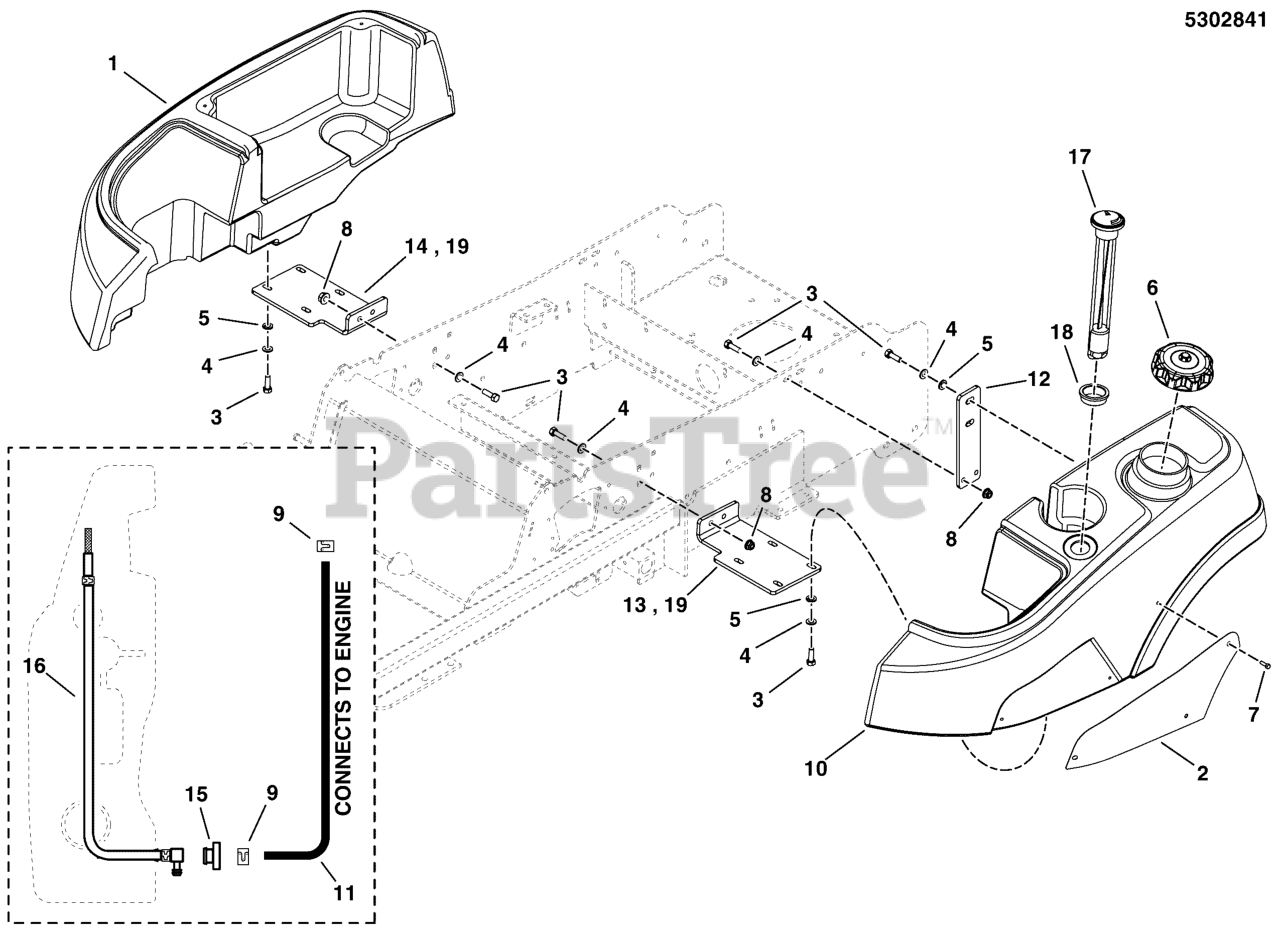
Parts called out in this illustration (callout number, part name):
1	TANK, FENDER, RH
2	PLATE,FUEL TANK BADGE
3	BOLT, 5/16-18 X 3/4 GD5
4	WASHER, 5/16" SAE
5	WASHER, 5/16 LOCK CZ
6	FUEL CAP, 3-1/2", MANAGED VENT OUT, 12"
7	SCREW, #10-24 X 3/8 ALLEN BHBZ
8	NUT, 5/16-18 HEX NYLOCK FLANGE
9	CLAMP, HOSE, EXTERNAL, 1/2 - RED
10	TANK, FUEL, LH
11	HOSE, 1/4" FUEL, 20.00"
12	MOUNT, FUEL TANK, REAR - BLK
13	MOUNT, FUEL TANK, FRONT - BLK
14	MOUNT FENDER, FRONT - BLK
15	BUSHING-FUEL TANK RED RUBBER
16	PICKUP TUBE ASM, FUEL TANK
17	GAUGE, FUEL LEVEL
18	GROMMET, FUEL GAUGE
19	MOUNT, FENDER, FRONT - BLK
